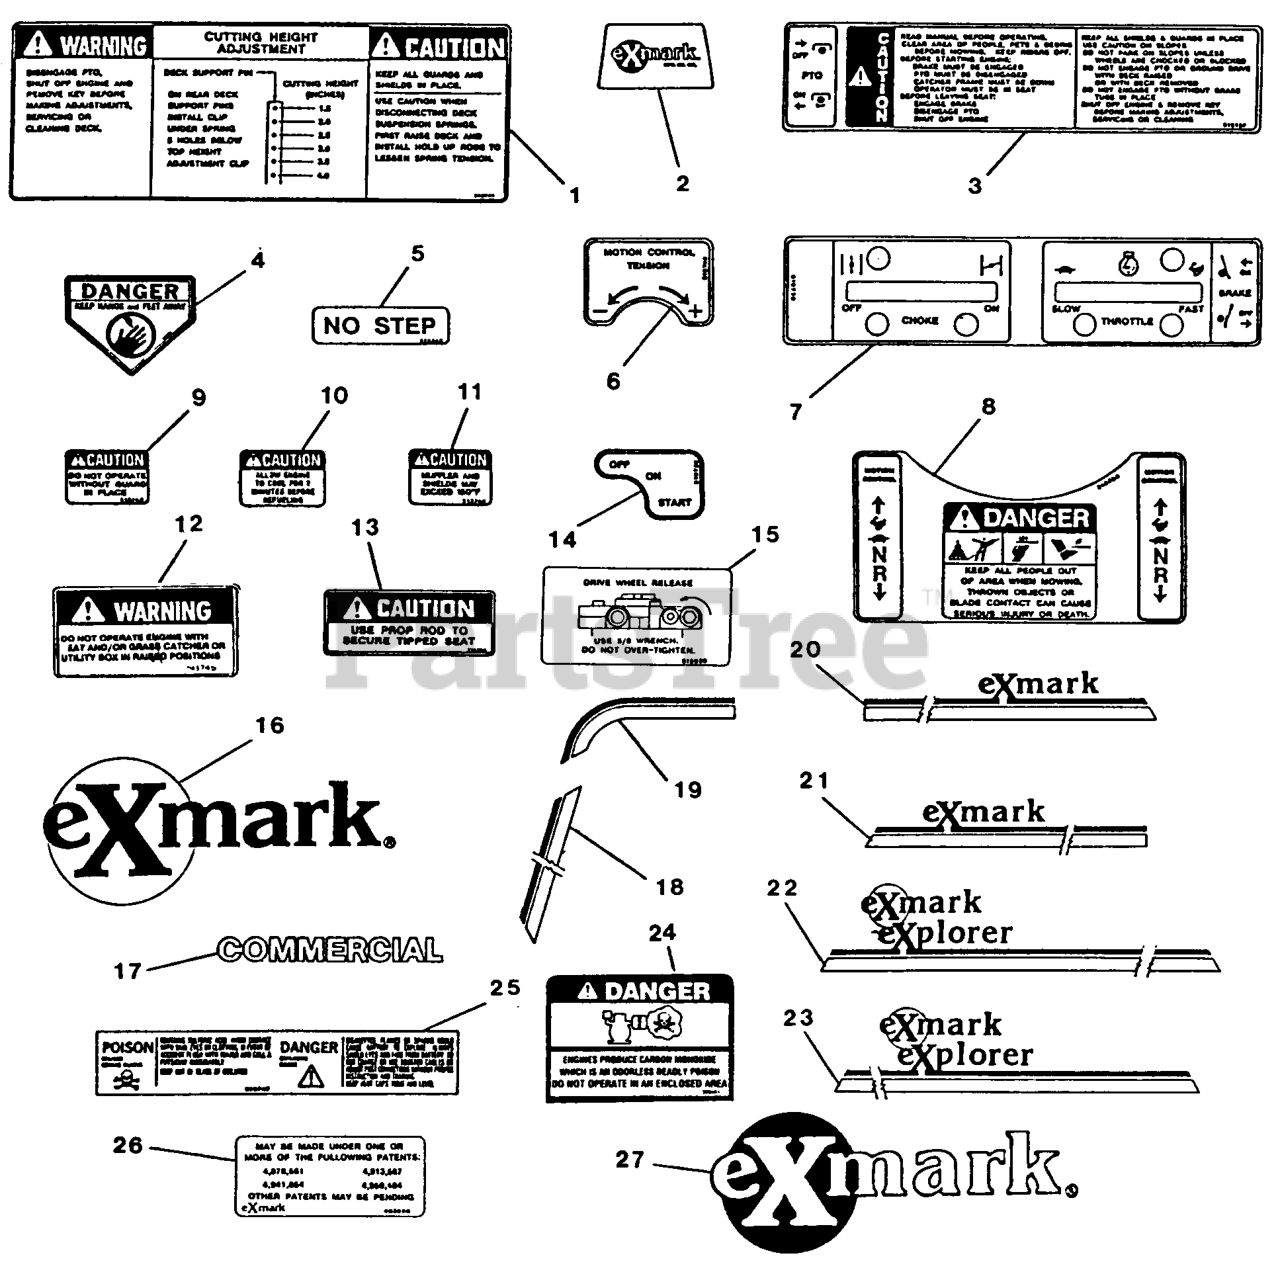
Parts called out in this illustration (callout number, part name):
3	DECAL,FENDER RH
4	DECAL-DANGER
5	DECAL,NO STEP
8	DECAL,CONSOLE
9	DECAL-GUARD
25	DECAL-BATTERY
